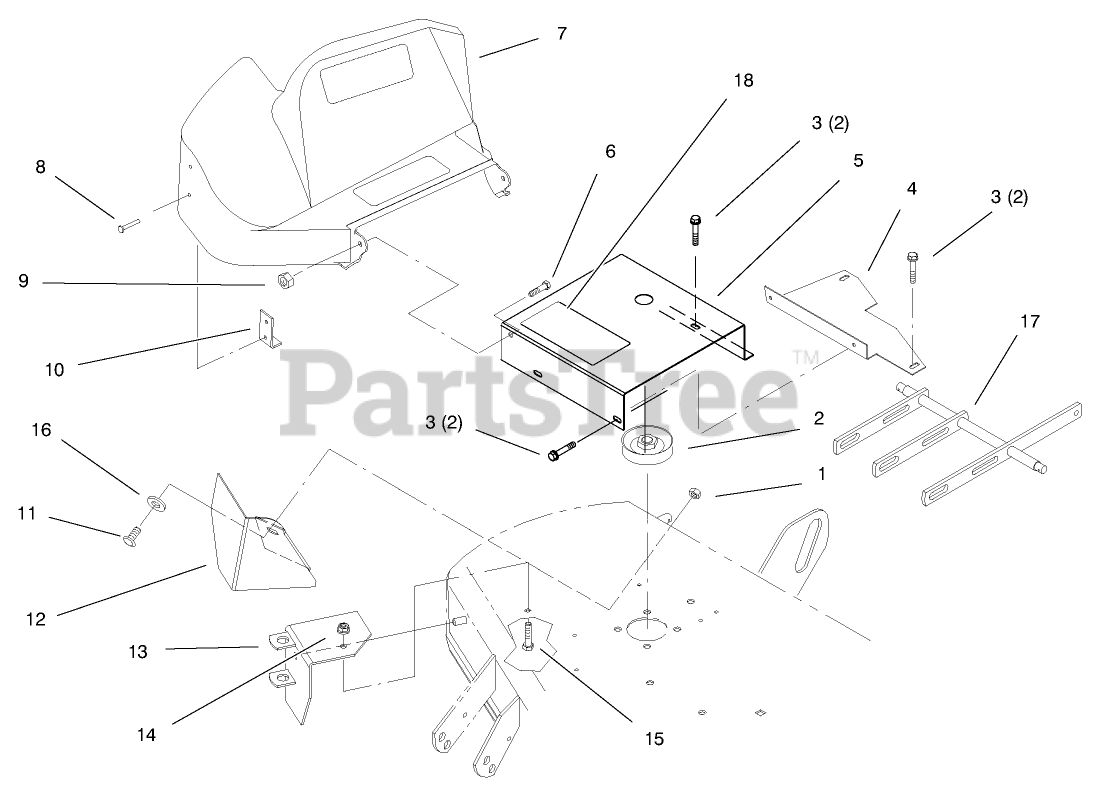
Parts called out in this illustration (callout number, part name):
1	NUT-LOCK, NI
2	PULLEY
3	SCREW-HWH
5	SHIELD / DECAL ASM
6	SCREW-HH
7	SHIELD-BELT
8	RIVET-POP
9	NUT-LOCK, NI
10	BRACKET-SUPPORT, SHIELD
11	SCREW-HH
14	NUT-HF
15	SCREW-HH
16	WASHER-FLAT
18	DECAL-DANGER
